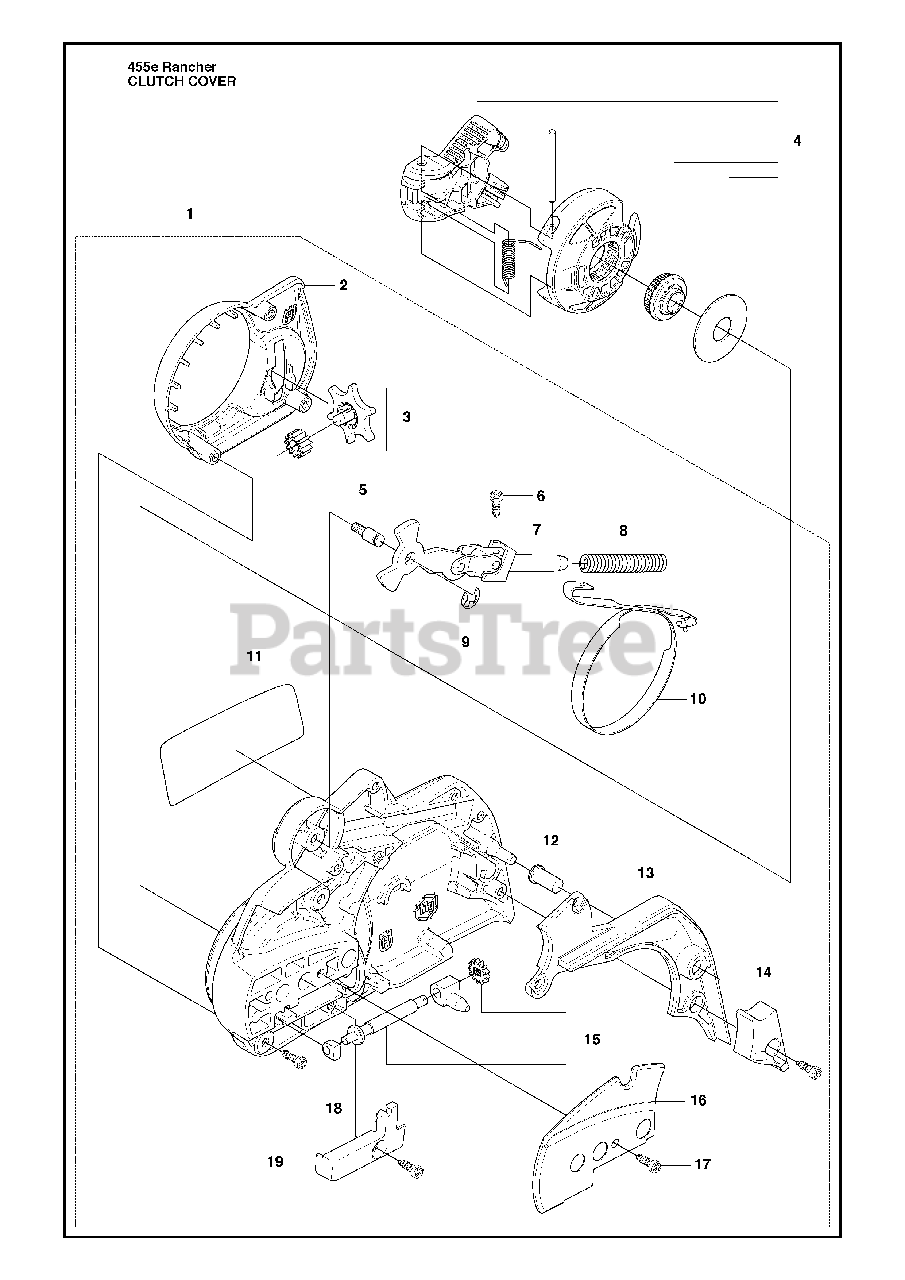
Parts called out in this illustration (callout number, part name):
1	CLUTCH HOUSING COMPLETE
2	HEAT SHIELD
3	CHAIN TENSIONER WHEEL, COMP.
4	KNOB, COMPLETE
10	BRAKE BAND
11	DECAL, CLUTCH HOUSING
13	COVER, CHAIN BRAKE
14	WEAR GUARD, CHAIN
15	CHAIN TENSIONER SCREW, COMP.
16	WEAR PLATE
18	BEARING SLEEVE
